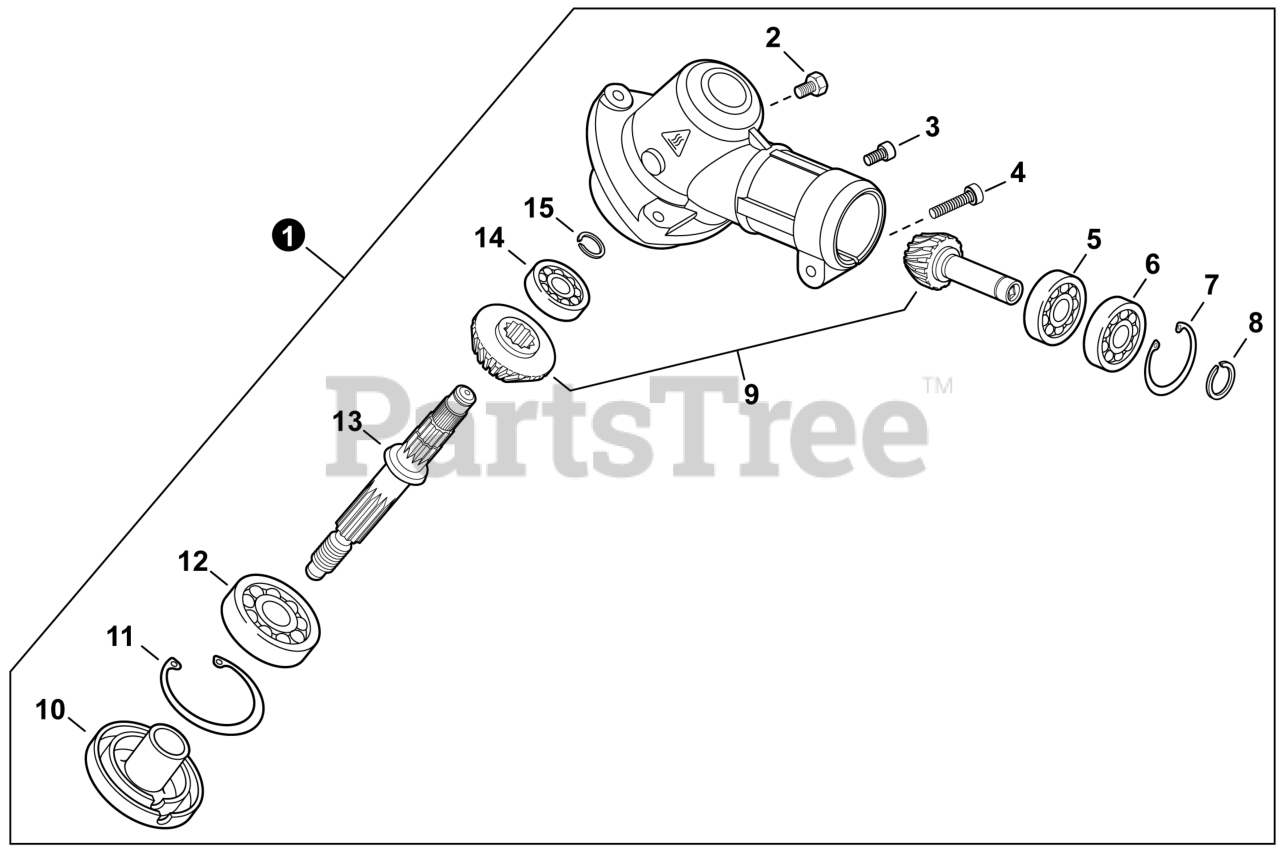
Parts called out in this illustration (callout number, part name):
1	GEAR CASE ASSY
2	BOLT M8×8
3	BOLT, TORX 5×12
4	BOLT, TORX 5×25
5	BEARING, BALL 6900
6	BEARING, BALL 6900Z
7	RING, SNAP Ø22
8	RING, SNAP Ø10
9	GEAR SET, BEVEL
10	PLATE, ADAPTOR - UPPER
11	RING, SNAP Ø42
12	BEARING, BALL 6302
13	SHAFT, GEAR
14	BEARING, BALL 629
15	RING, SNAP Ø12
